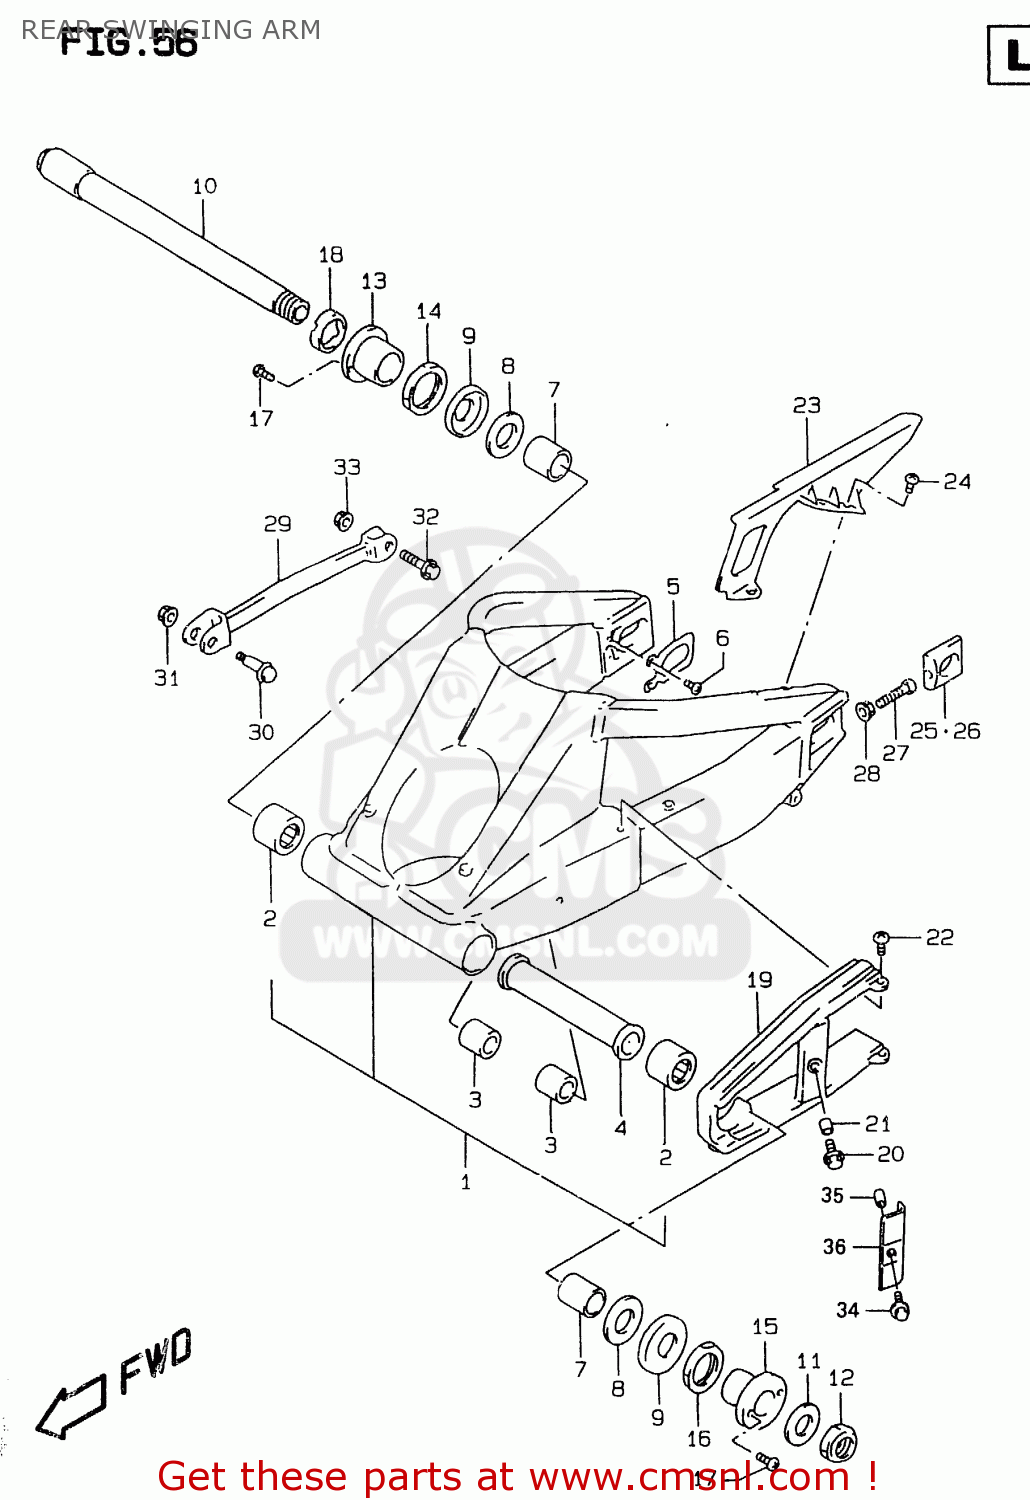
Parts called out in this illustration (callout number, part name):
1	SWINGINGARM ASSY,RR
2	BEARING(30X40X25)
3	BEARING(17X24X20)
4	SPACER COMP,REAR SWING PIVOT
5	PLATE,RR SWING ARM BRKT
6	SCREW 6X10
7	SPACER,REAR SWING ARM PIVOT
8	WASHER
9	DUST SEAL,RR SWGARM PIVOT
10	SHAFT,RR SWINGINGARM PIVOT
11	WASHER(25.2X42X3.2)
12	NUT
13	BOSS,RR SWINGINGARM PIVOT,R
14	NUT,RR SWGARM PIVOT BOSS,R
15	BOSS,RR SWINGINGARM PIVOT,L
16	NUT,RR SWGARM PIVOT BOSS,L
17	SCREW
18	NUT,REAR SWING ARM PIVOT
19	BUFFER,CHAIN TOUCH DEFENSE
20	BOLT 6X20,WITH PLAIN WASHER
21	SPACER(6.5X10X8)
22	SCREW
23	CASE,CHAIN
24	SCREW(6X16)
25	ADJUSTER,CHAIN,R
26	ADJUSTER,CHAIN,L
27	BOLT(8X50)
28	NUT
29	TORQUELINK,RR
30	BOLT
31	NUT
32	BOLT(10X37)
33	NUT
34	BOLT
35	SPACER(6.5X10X10)
36	PLATE,CHAIN BUFFER
